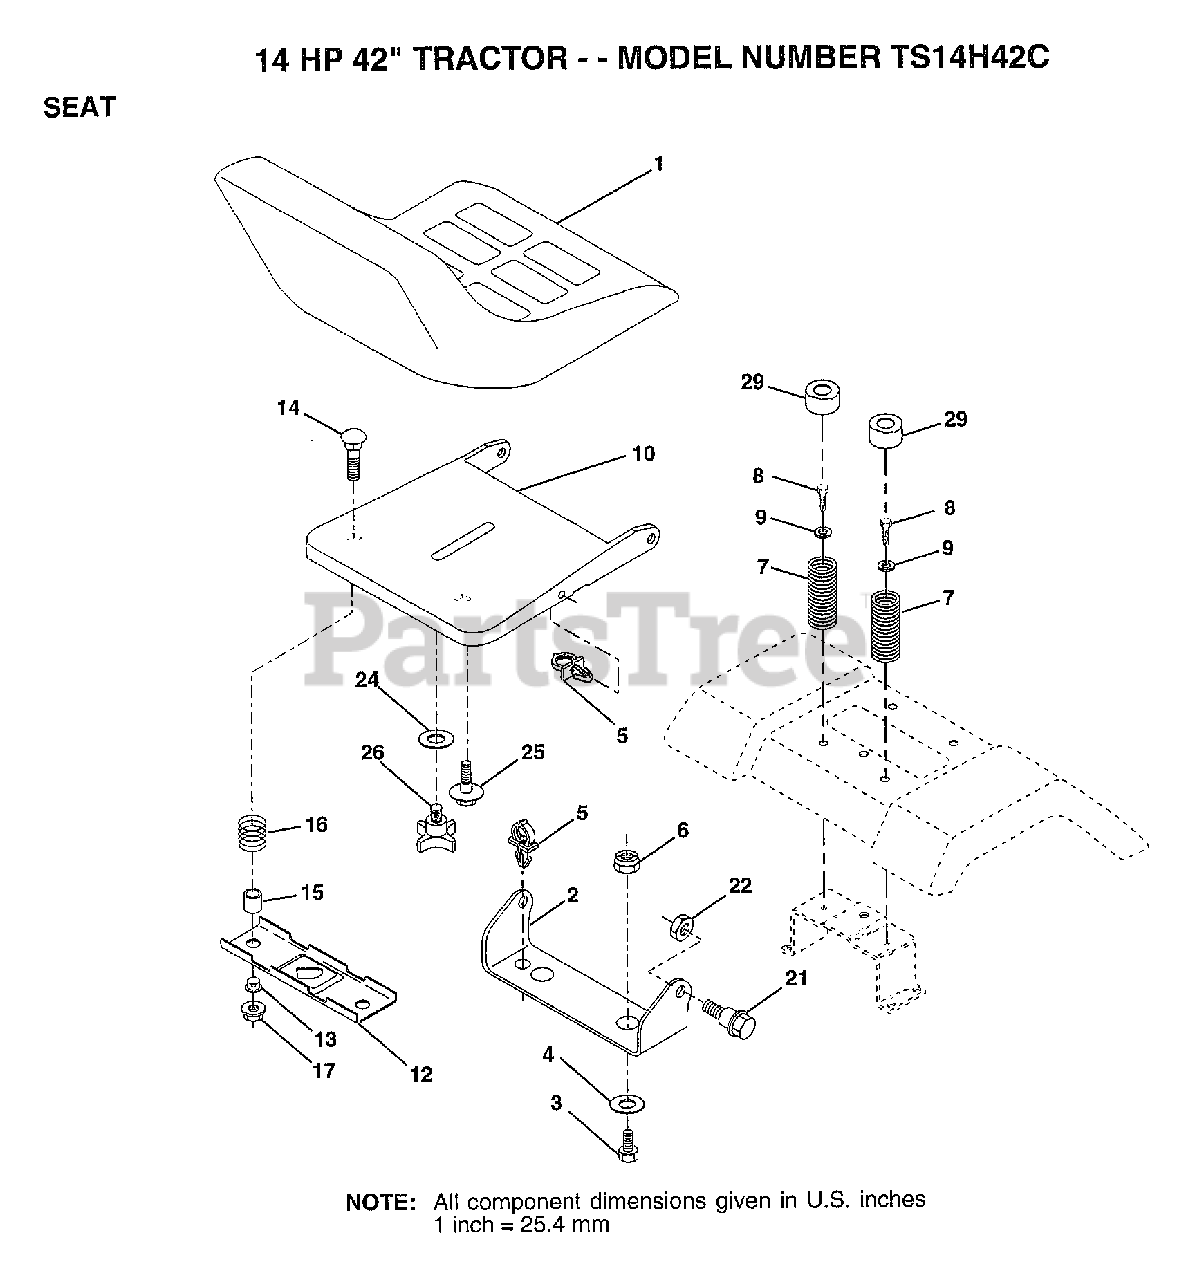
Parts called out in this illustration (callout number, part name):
2	BRACKET PVT SEAT
3	BOLT
4	WASHER PM
5	CLIP PUSH - IN
6	NUT
7	SPRING COMPRESSIO
8	SCREW GTV
9	WASHER
12	BRKT SWITCH
13	BUSHING
15	SPLIT SPACER
16	SPRING
21	BOLT.SHLD.5/16-18
22	NUT
24	WASHER
25	"BOLT,SHOULDER"
26	"KNOB 1/2"" YT"
29	CAP SPRING
